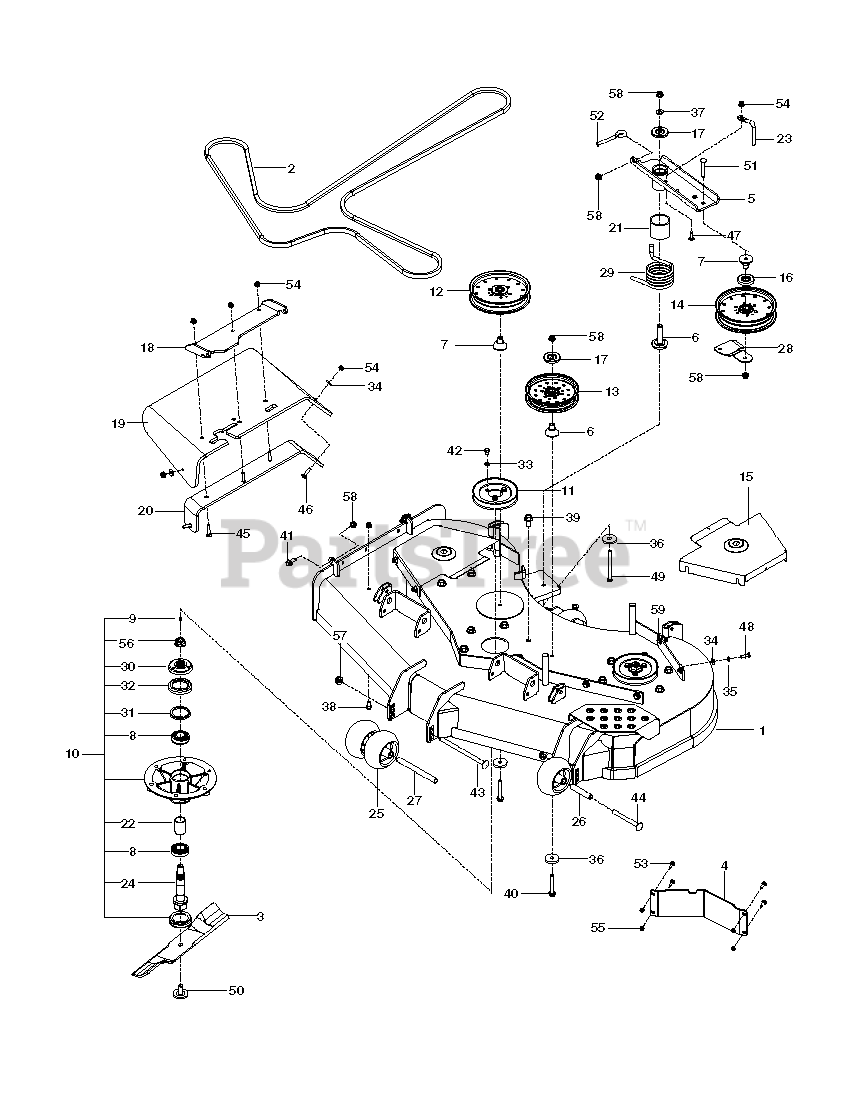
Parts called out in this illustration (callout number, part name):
1	DECK.FAB.54".W/DECALS.ORANGE
2	RP_BELT, "5V", 169.75"
3	BLADE, 19"
4	BAFFLE, DIVERTER 54"/60" LH
5	ASSY, IDLER ARM, PZ
6	BEARING, IDLER PIVOT
7	BEARING, IDLER ARM
8	BEARING - 206KRR8
9	ZERK
10	SPINDLE ASM. 10"
11	PULLEY - 5.93 OVER PINS
12	PULLEY - 7" NARROW
13	PULLEY IDLER, 6" NARROW
14	PULLEY - IDLER 7"
15	SHIELD,BELT, 60" ORANGE
16	SHIELD, DUST
17	DUST SHIELD
18	BRKT - CHUTE MTG BLACK
19	CHUTE, DISCHARGE 48-52
20	BRKT, CHUTE SUPPORT BLACK
21	SPACER, IDLER PIVOT
22	SPACER - BEARING
23	BELT KEEPER
24	SHAFT - SPINDLE
25	ROLLER, GAUGE .635 BORN
26	TUBE, ROLLER AXLE
27	TUBE, ROLLER AXLE LONG
28	BELT.GUIDE.BLACK
29	SPRING, TORSION, IDLER
30	HUB - PULLEY
31	V-RING, 55MM
32	CUP - DEBRIS
33	WASH 5/16 DISC SPRING ZD
34	WASHER 5/16 FLAT
35	WASHER.LOCK.HVY.HLCL.SPR.5/16
36	SPINDLE WASHER
37	WASHER, 3/8 THICK
38	HHFS 5/16-18 X 3/4
39	HHFS 1/2-13 X 1 GR5 ZD
40	HHFS 3/8-16 X 2 3/4
41	HHFS 3/8-16 X 1 GRD 5 ZD
42	HCS 5/16-18 X 1/2 GR 5 ZD
43	RHSNB 1/2-13 X 8 GR5 ZD
44	RHSNB 1/2-13 X 4.75 GR5 ZD
45	RHSNB 5/16-18 X 1-1/2 GR 5 ZD
46	BOLT, CARRIAGE 5/16X1-1/4
47	RHSSNB 5/16C X 1.0
48	HCS 5/16C X 1
49	HCS 3/8-16 X 4-1/2 GR 8 ZD
50	BLADE BOLT/WASHER
51	CARRIAGE BOLT 3/8-16 X
52	EYE BOLT, 3/8 X 4"
53	1/4-20X3/4 CARR BLT
54	5/16-18 NYLOC FLANGE NUT
55	NUT.1/4-20.HEX.NYLOC.ZD
56	NUT FLANGE 3/4-16
57	NUT, 1/2-13 HEX FLG NYLOC ZD
58	NUT 3/8-16 HEX FLG NYLOC ZD
59	U-CLIP 5/16-18 NUT RETAINER
